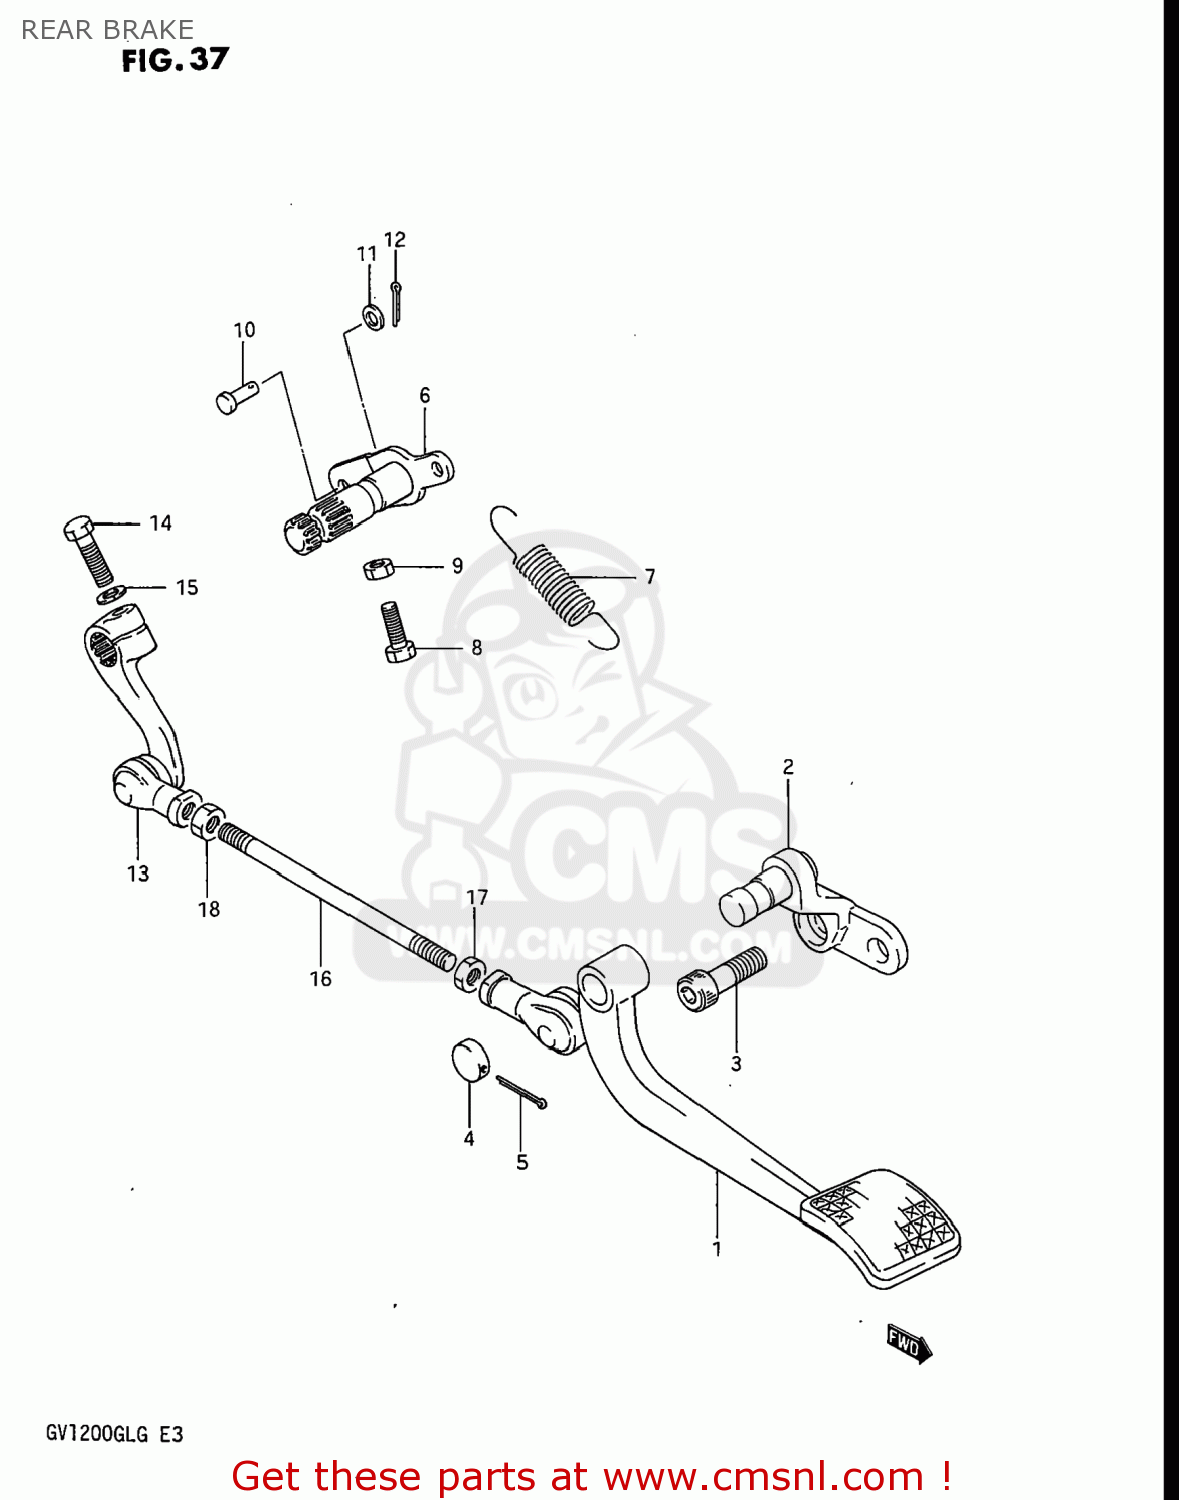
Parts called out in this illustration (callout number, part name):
1	PEDAL ASSEMBLY,BRAKE PEDAL
2	BAR,BRAKE PEDAL BOSS
3	BOLT
4	CAP,BRAKE PEDAL
5	COTTER PIN
6	ARM,BRAKE PEDAL
7	SPRING
8	BOLT(6X23)
9	NUT 6MM
10	PIN
11	WASHER
12	PIN
14	BOLT
15	LOCK WASHER
16	LINK,BRAKE PEDAL
17	NUT
18	NUT
